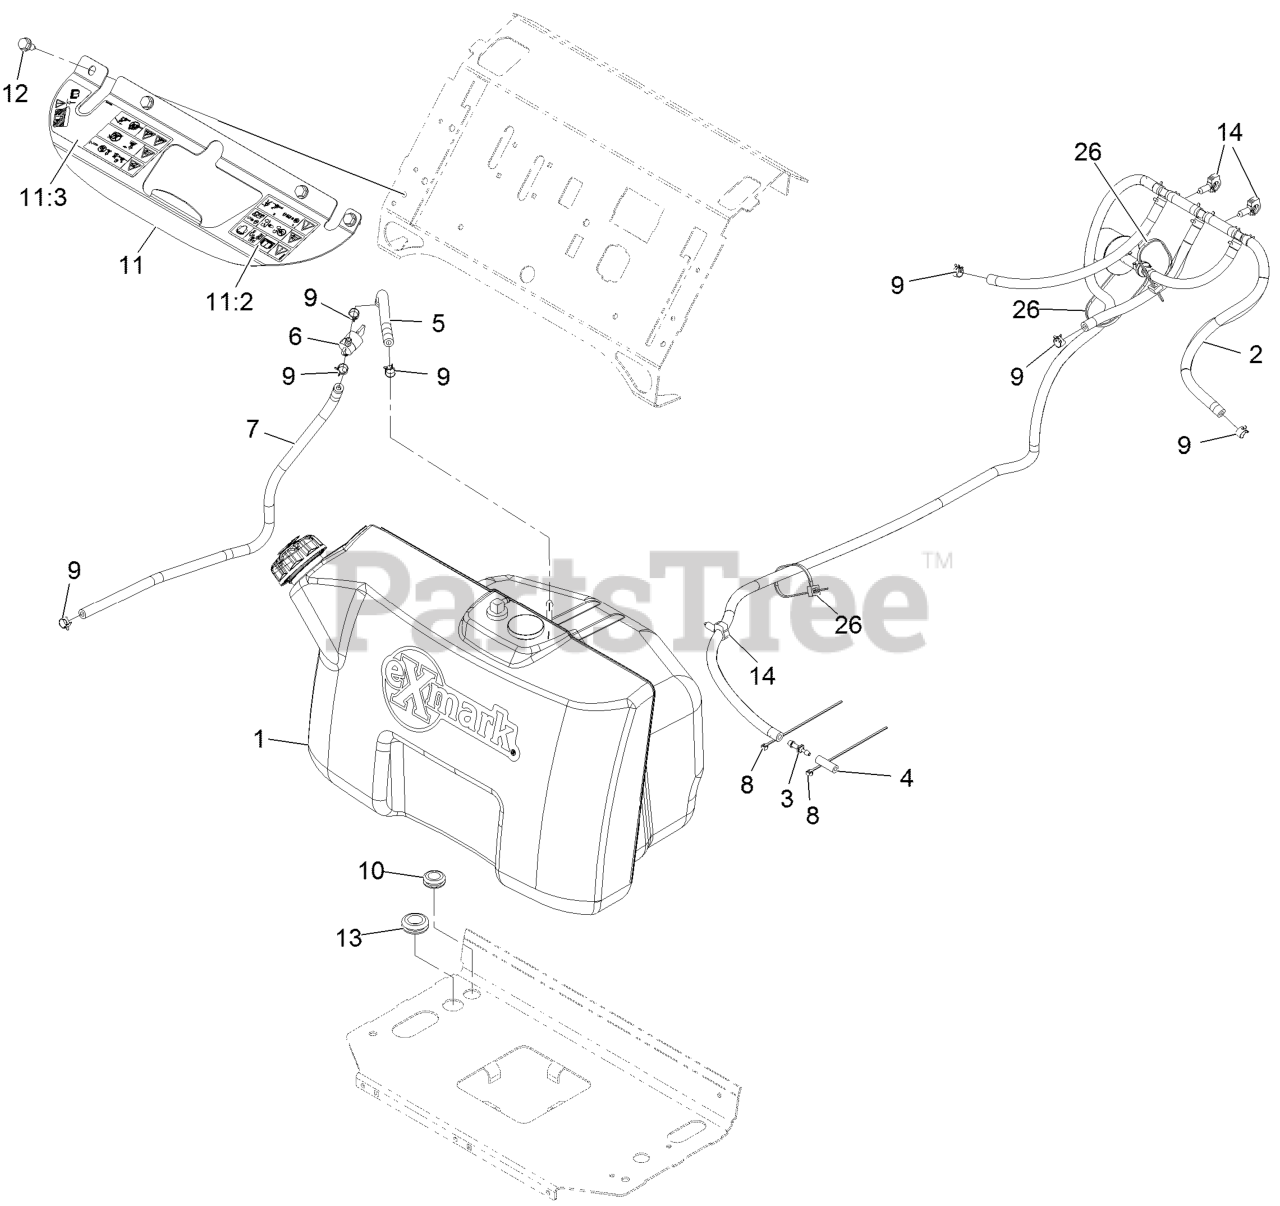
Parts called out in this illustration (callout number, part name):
2	VENT ASM
3	FITTING-STRAIGHT
4	HOSE-FUEL
5	HOSE-FUEL
6	VALVE-FUEL
7	HOSE-FUEL
8	TIE-CABLE
9	CLAMP-HOSE
10	GROMMET
11	BRACKET-TANK
11:2	DECAL-WARNING LH
11:3	DECAL-WARNING RH
12	Screw-HWH 5/16-18 X 3/4 Tf
13	GROMMET
14	CLIP-HARNESS
26	TIE-CABLE
